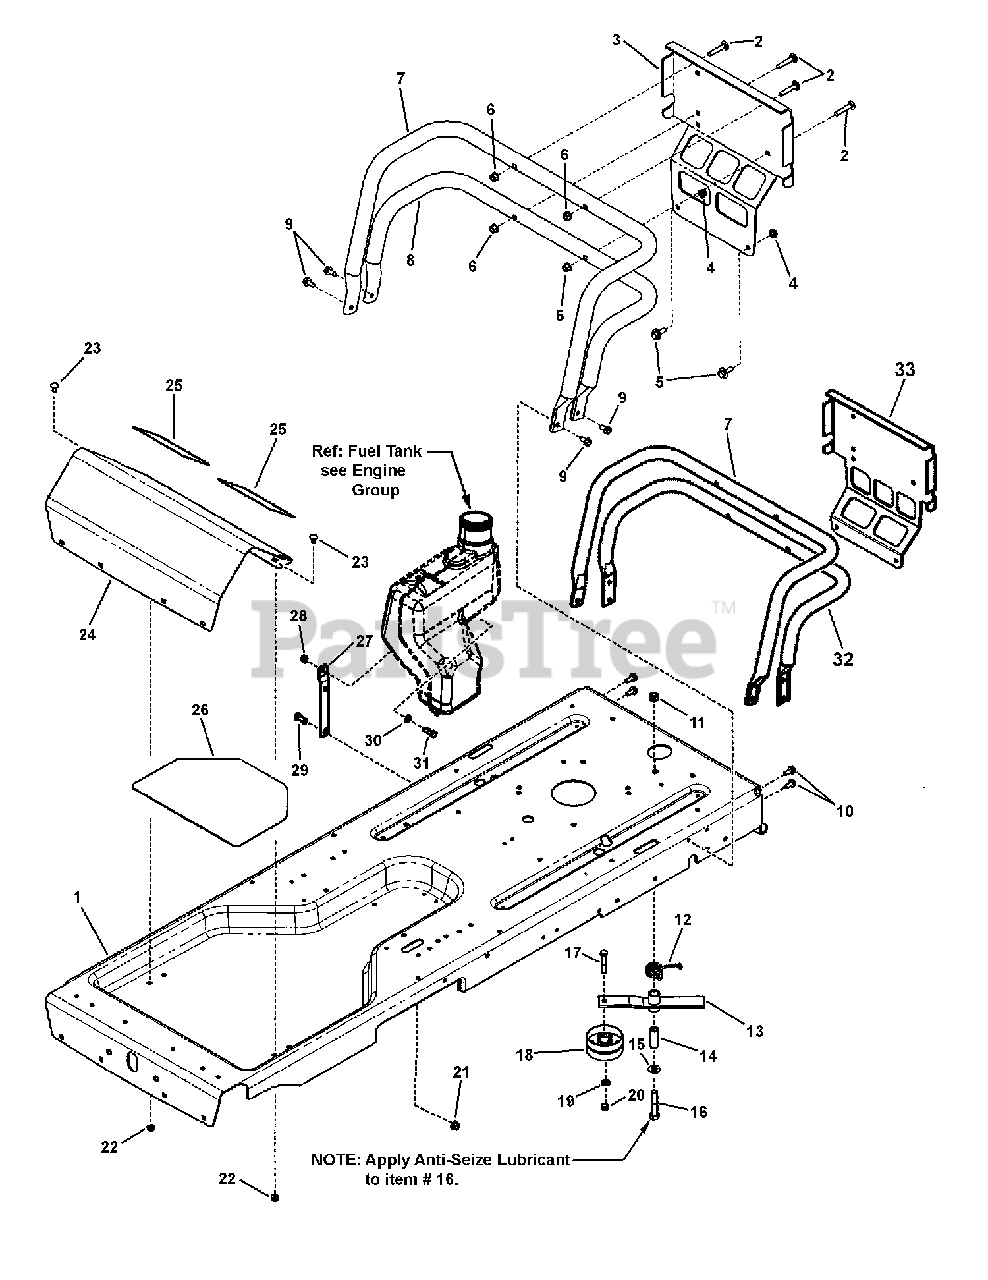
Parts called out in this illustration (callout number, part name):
1	FRAME, RZT
2	BOLT, 5/16-18 x 1-3/4" Round Head Short Square Neck
3	PLATE, Brand (Replace By 1753572)
4	NUT, 5/16-18 Hex Flange Lock, Large, Black
5	BOLT, Shoulder
6	NUT, 5/16-18 Hex Flange Nyloc
7	TUBE, Bumper, Upper, 285Z
8	TUBE, Bumper, Lower, 285Z
9	SCREW, 5/16-18 x 3/4" Hex Washer Head Self-Tap, Black
10	SCREW, 5/16-18 x 3/4" Hex Washer Self-Tap, YZ
11	NUT, 1/2-13 Hex Center Lock, GR 5, YZ
12	SPRING, Torsion, RH Wind
13	WELDMENT, Hydro Idler MY08
14	SPACER, Hydro Idler
15	WASHER, .531 x 1.062 x .121, Flat, YZ (SAE)
16	SCREW, 1/2-13 x 2-1/2", Hex Head Cap, GR 5 (Black Phosphate)
17	SCREW, 3/8-16 x 2" Hex Head Cap, GR 5, YZ
18	PULLEY, Backside Idler, 3.25" OD x .391 ID x 1.63
19	WASHER, 3/8" Flat (SAE)
20	NUT, 3/8-16 Hex Center Lock, YZ
21	NUT, 3/8-16 Hex Flange lock, GR F, BZ
22	NUT, 5/16-18, Hex Flange Lock, GR 5
23	BOLT, 5/16-18 x 5/8" Round Head Short Square Neck Carriage, GR 5
24	FOOTREST, Snapper
25	FOOT PAD
25	MAT, Floor Pan, RZT (13-1/4" H)
26	MAT, Floor Pan, RZT (12-1/4" H)
27	BRACKET, Support, Fuel Tank
28	NUT, 5/16-18, Nyloc, YZ
29	SCREW, 3/8-16 x 3/4" Hex Head Cap, GR 5 ZP
30	WASHER, .34 x .62 x 16 Ga, Flat
31	SCREW, 5/16-18 x 1" Hex Head Cap, GR 5, YZ
32	TUBE, Bumper, Lower, 285Z
33	PLATE, Brand
